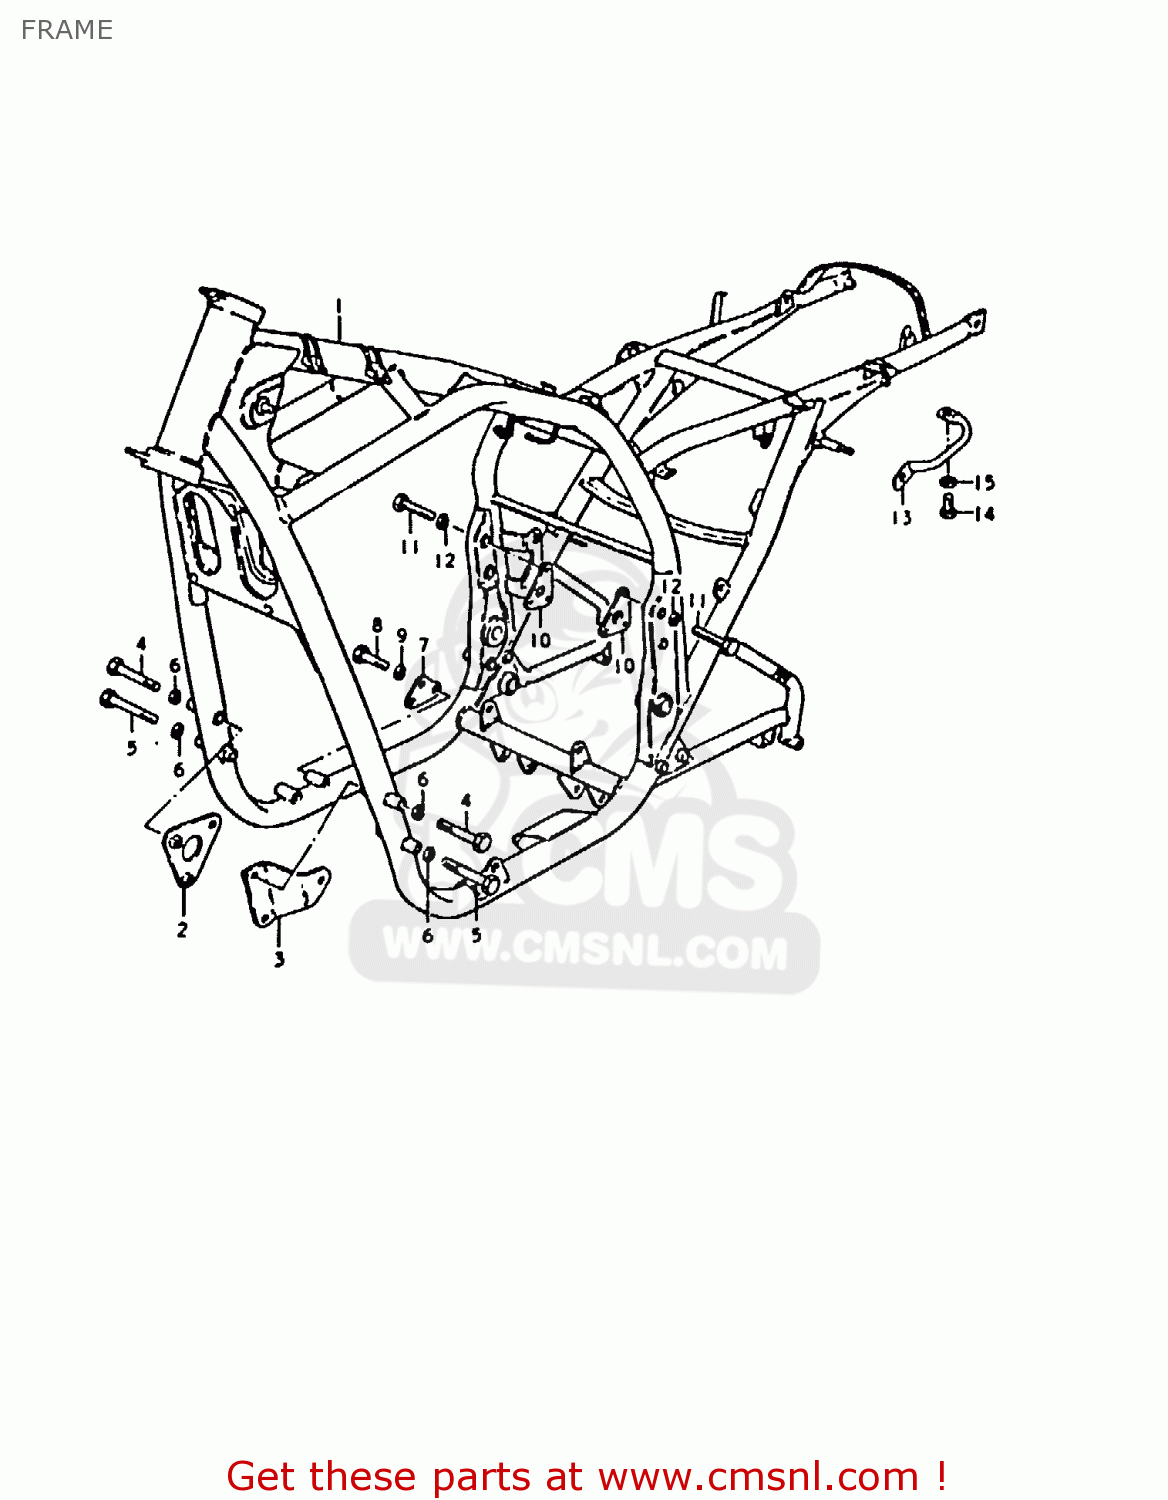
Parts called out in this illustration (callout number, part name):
1	FRAME
2	PLATE,ENGINE MOUNTING
3	PLATE,ENGINE MOUNTING
4	BOLT
5	BOLT
6	LOCK WASHER
7	PLATE,ENGINE MOUNTING
8	BOLT
9	LOCK WASHER
10	PLATE,ENGINE MOUNTING
11	BOLT
12	LOCK WASHER
13	GRIP,FRAME
14	BOLT
15	WASHER
